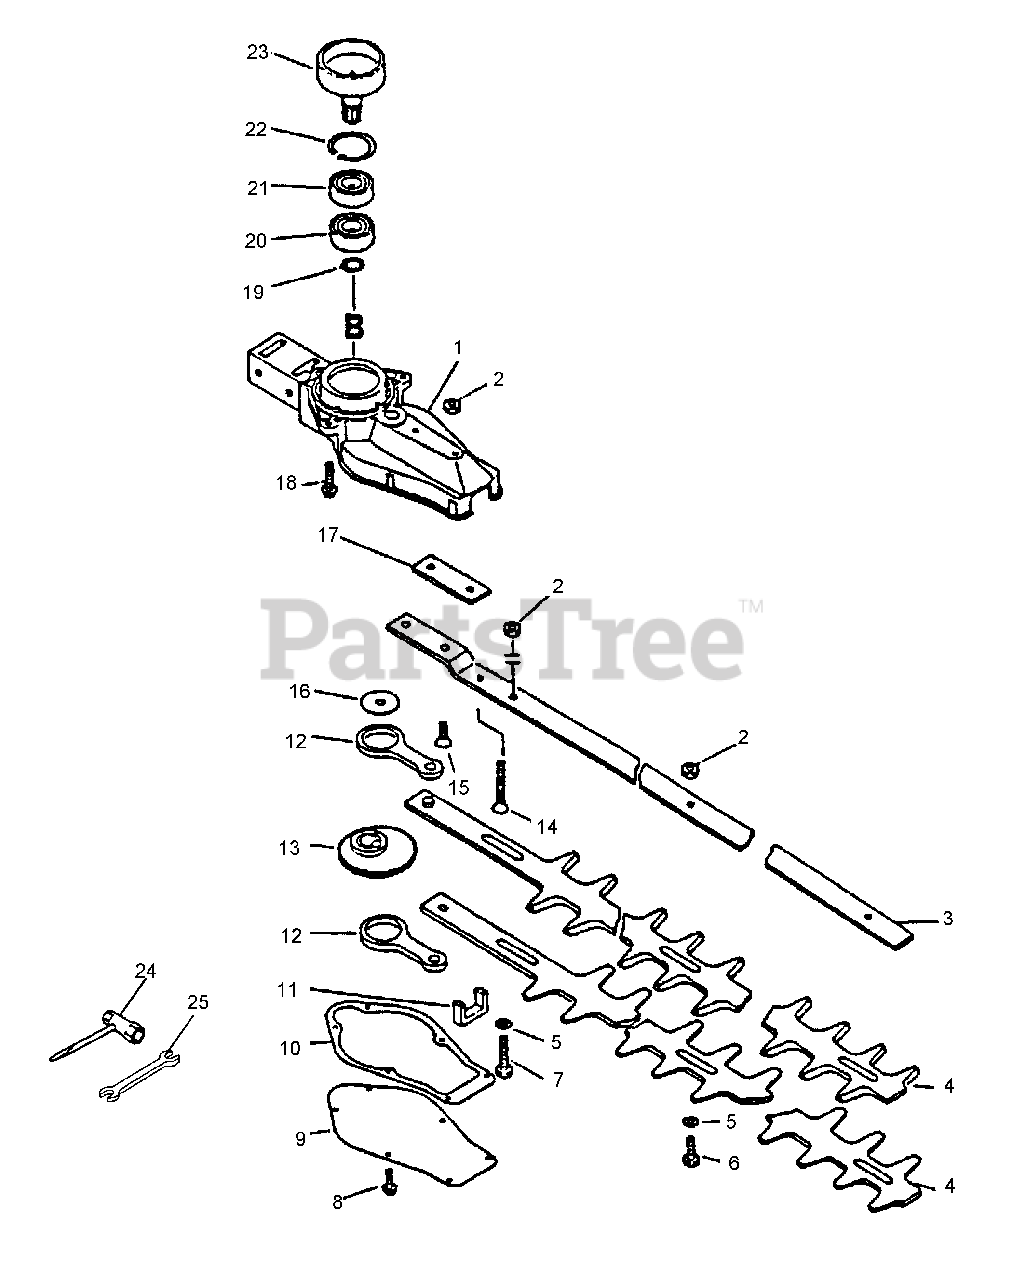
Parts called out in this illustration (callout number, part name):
1	CASE, GEAR
2	LOCKNUT - 6
3	SUPPORT, BLADE - 20" (50cm)
4	BLADE - 20" (50cm)
5	WASHER - 6
7	BOLT - 6X35
8	SCREW - 4X10
9	LID, GEAR CASE
10	GASKET, GEAR CASE
11	SEAL, FELT
12	ROD, CONNECTING
13	GEAR - DRIVE
14	SCREW - 5X30
15	SCREW - 6X25
18	SCREW - 5X20
19	RING, RETAINING - 14
20	BEARING, BALL - 6202
21	BEARING, BALL - 6202
22	RING, RETAINING - 35
23	DRUM, CLUTCH
24	T-WRENCH - 13X19mm
25	SPANNER - 8X10mm
